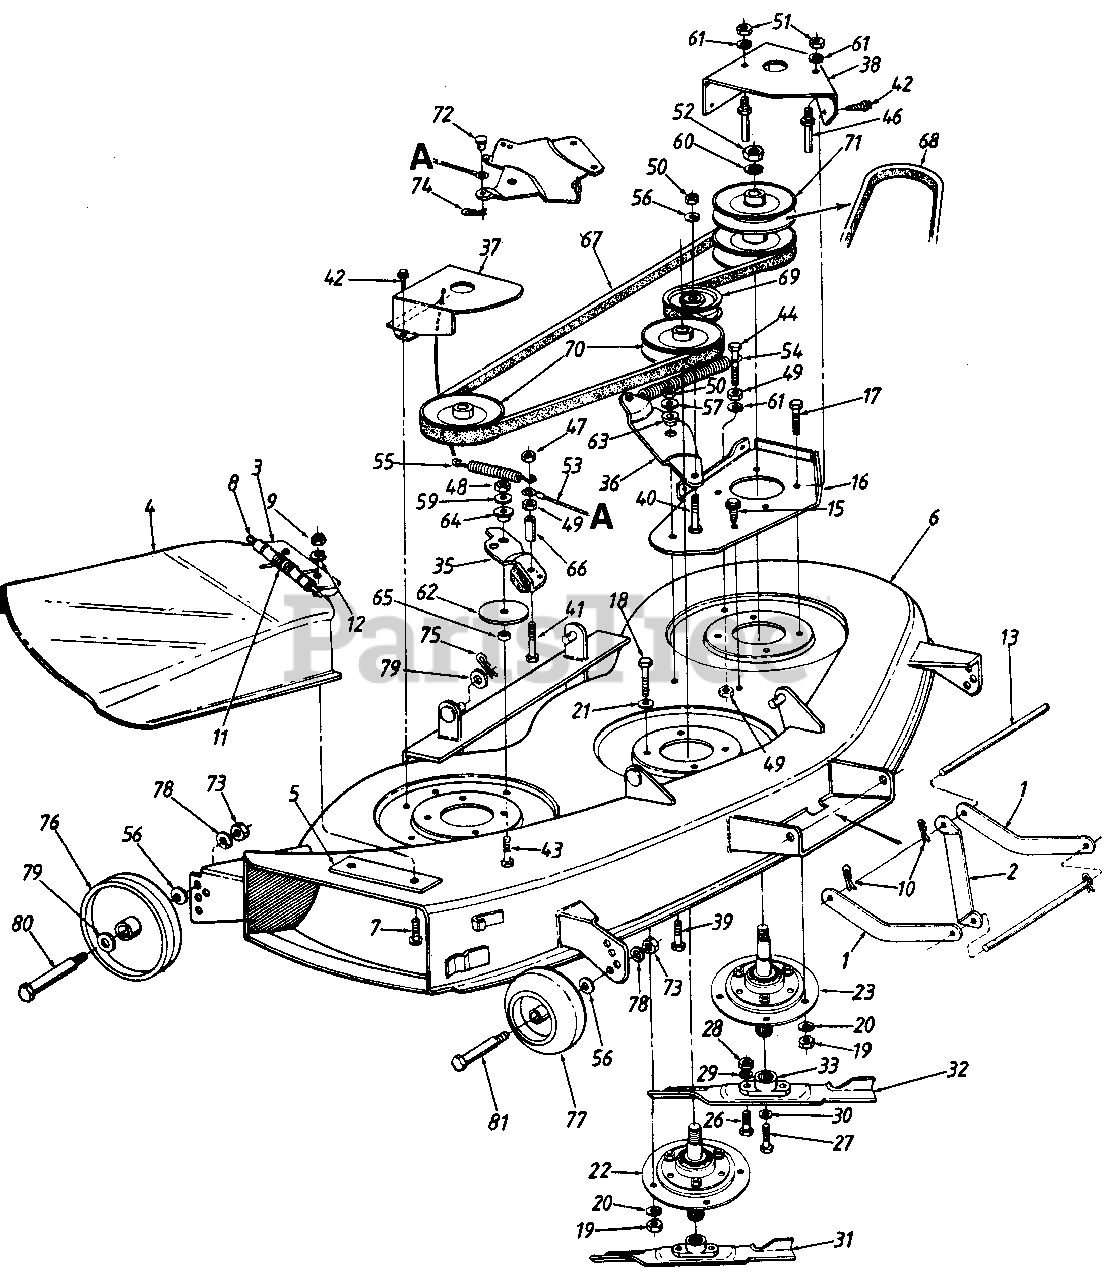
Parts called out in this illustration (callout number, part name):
4	Deck Chute
5	Chute Mtg. Plate
6	46" Deck Ass'y.
7	Truss Mach. Scr. 1/4-20 x .75"
8	Hinge Pin
9	Hex Jam Nut 1/4-20 Thd.
10	Int. Cotter Pin
11	Torsion Spring
12	Bell-Wash. 1/4" I.D.
13	Deck Connecting Rod
15	Hex TT-Tap Scr. 5/16-18 x .62
18	Hex Bolt 5/16-24 x .75" Lg.
19	Hex Nut 5/16-24 Thd.
20	L-Wash. 5/16" l.D.
21	Bell-Wash. 6/16" l.D.
22	Spindle Ass'y.
23	Spindle Ass'y.
26	Hex Bolt 5/16-24 x 1.25n Lg. (Grade 5)
27	Hex Cl-Bolt 3/8-24 x .88n Lg.
28	Hex Nut 5/16-24 Thd.
29	L-Wash. 5/16" l.D.
30	L-Wash. 3/8" l.D.-H.D.
31	High Lift Blade 14.88" Lg.
32	High Lift Blade 16.28"
33	Blade Adapter
35	Deck Brake Brkt. Ass'y.
36	Idler Bracket
40	Hex Bolt 3/8-24 x 1.5" Lg.
41	Hex Bolt 1/4-28 x 1.75" Lg.
42	Hex Wash. Hd. Tap-Scr. l/4-20 x .5" Lg
43	Hex Bolt 5/16-24 x 1.25n Lg. (Grade 5)
44	Hex Bolt 1/4-28 x 1.5n Lg.
46	Belt Guard Pin 1/4" Dia.
47	Hex Cent. L-Nut 1/4 28 Thd.
48	Hex Nut 5/16-24 Thd.
49	Hex Nut 1/4-28 Thd.
50	Hex Nut 3/8-24 Thd.
51	Hex Nut 1/4-20 Thd.
52	Hex Jam Nut 5/8-18 Thd.
53	Brake Cable Ass'y.
54	Extension Spring 6.12" Lg.
55	Extension Spring 3.97" Lg.
56	Bell-Wash. 38" l.D. x .88" O.D.
57	Bell-Wash. .39" l.D. x 1.13" O.D.
59	Bell Wash. .345" l.D. x .88"
60	Bell-Wash. 5/8" l.D. x 1.25" O.D.
61	L-Wash. 1/4" l.D.
62	Fl-Wash. 5/16" l.D. x 3" O.D.
63	Shld. Spacer.625" I.D.
64	Shld. Spacer
65	Spacer .34" l.D.
66	Spacer .326" l.D.
67	V-Belt
68	V-Belt
69	Fl-ldler wlFlanges 3.5" O.D.
70	Pulley 5.0" Dia.
71	Pulley 5.0" Dia.
72	Clevis Pin 1/4" Dia. x .53" Lg.
73	Hex Nut 318-16 Thd.
74	Intern. Cotter Pin 5/16" Dia.
75	Intern. Cotter Pin 3/8 Dia.
76	Deck Wheel 5" Dia.
77	Deck Wheel w/lnsert 5n Dia.
78	L-Wash. 3/8" l.D.
79	Fl-Wash. .531" l.D.
80	Shoulder Bolt .498" Dia. x 1.64" Lg.
81	Shoulder Bolt
